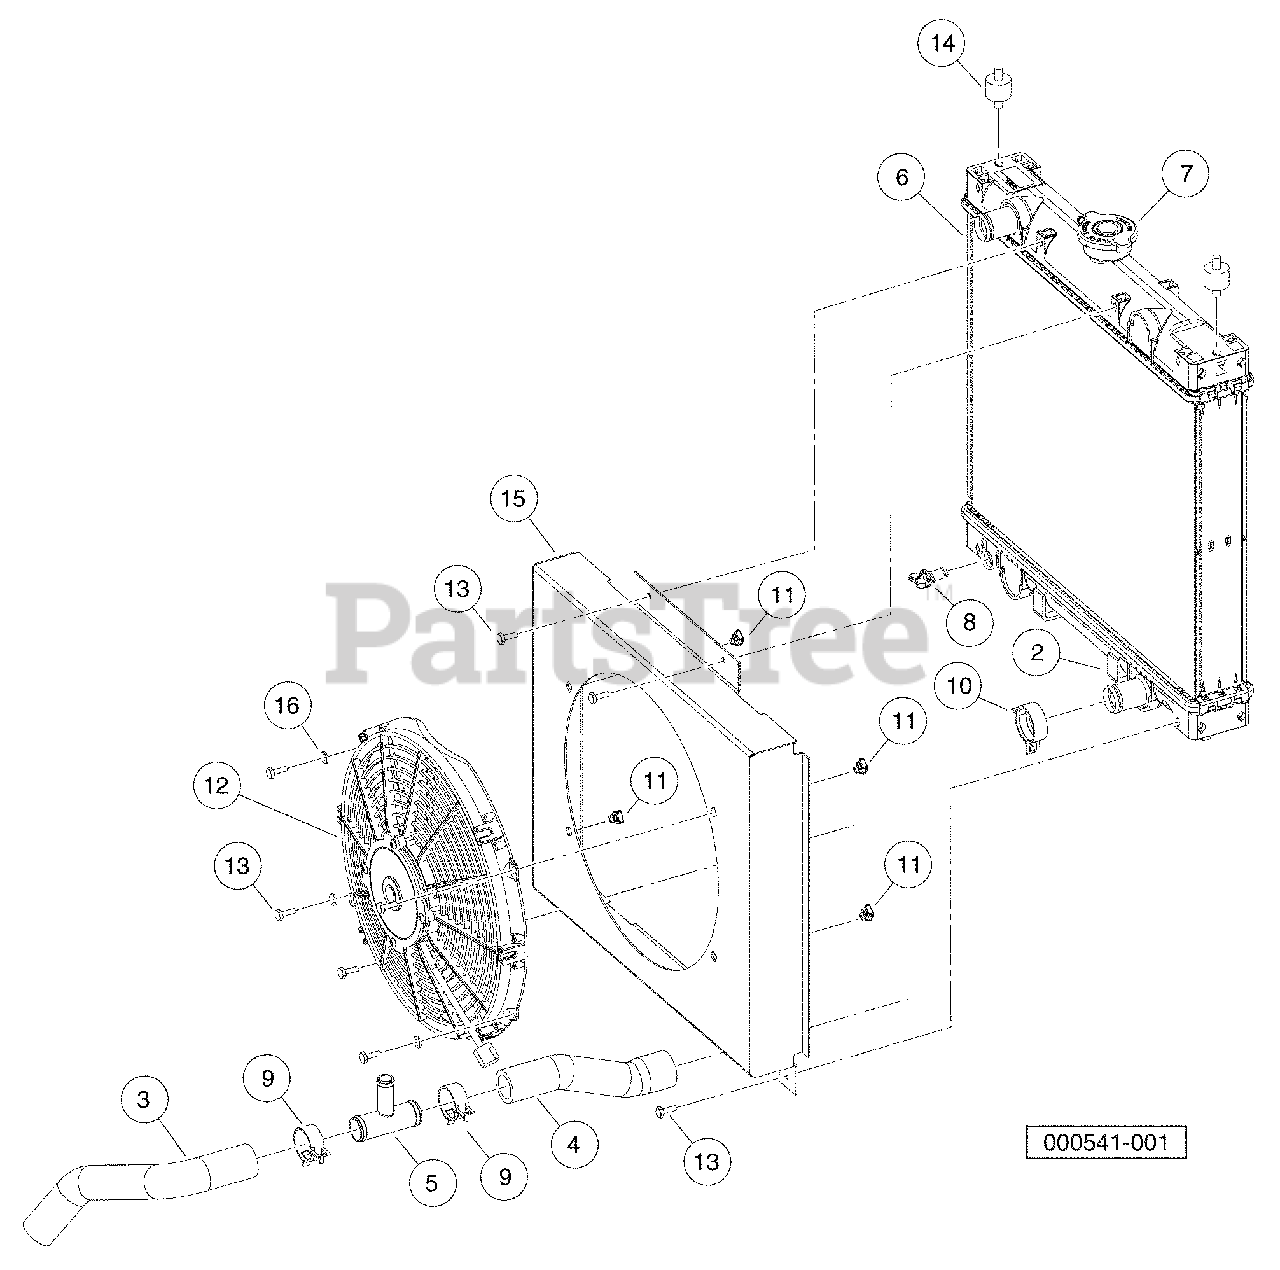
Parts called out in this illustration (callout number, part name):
1	Asm, Radiator
2	Tape, Vinyl Foam 1/8" x 3/4"
3	Hose, Coolant Lower Pipe
4	Hose, Coolant Lower Rad
5	Tee, Coolant Fill
6	Exchanger, Engine Coolant
7	Cap, Radiator
8	Drain Cock, Radiator
9	Clamp, Hose, Ctb 35mm
10	Clamp, Hose, Ctb 38mm
11	Nut, Self Retaining
12	Fan, Cooling 12 In Elect
13	Bolt, M6 X 1 X 16 Loctite
14	Isolator, Twin-Stud
15	Shroud, Radiator Fan
16	Washer, M6
